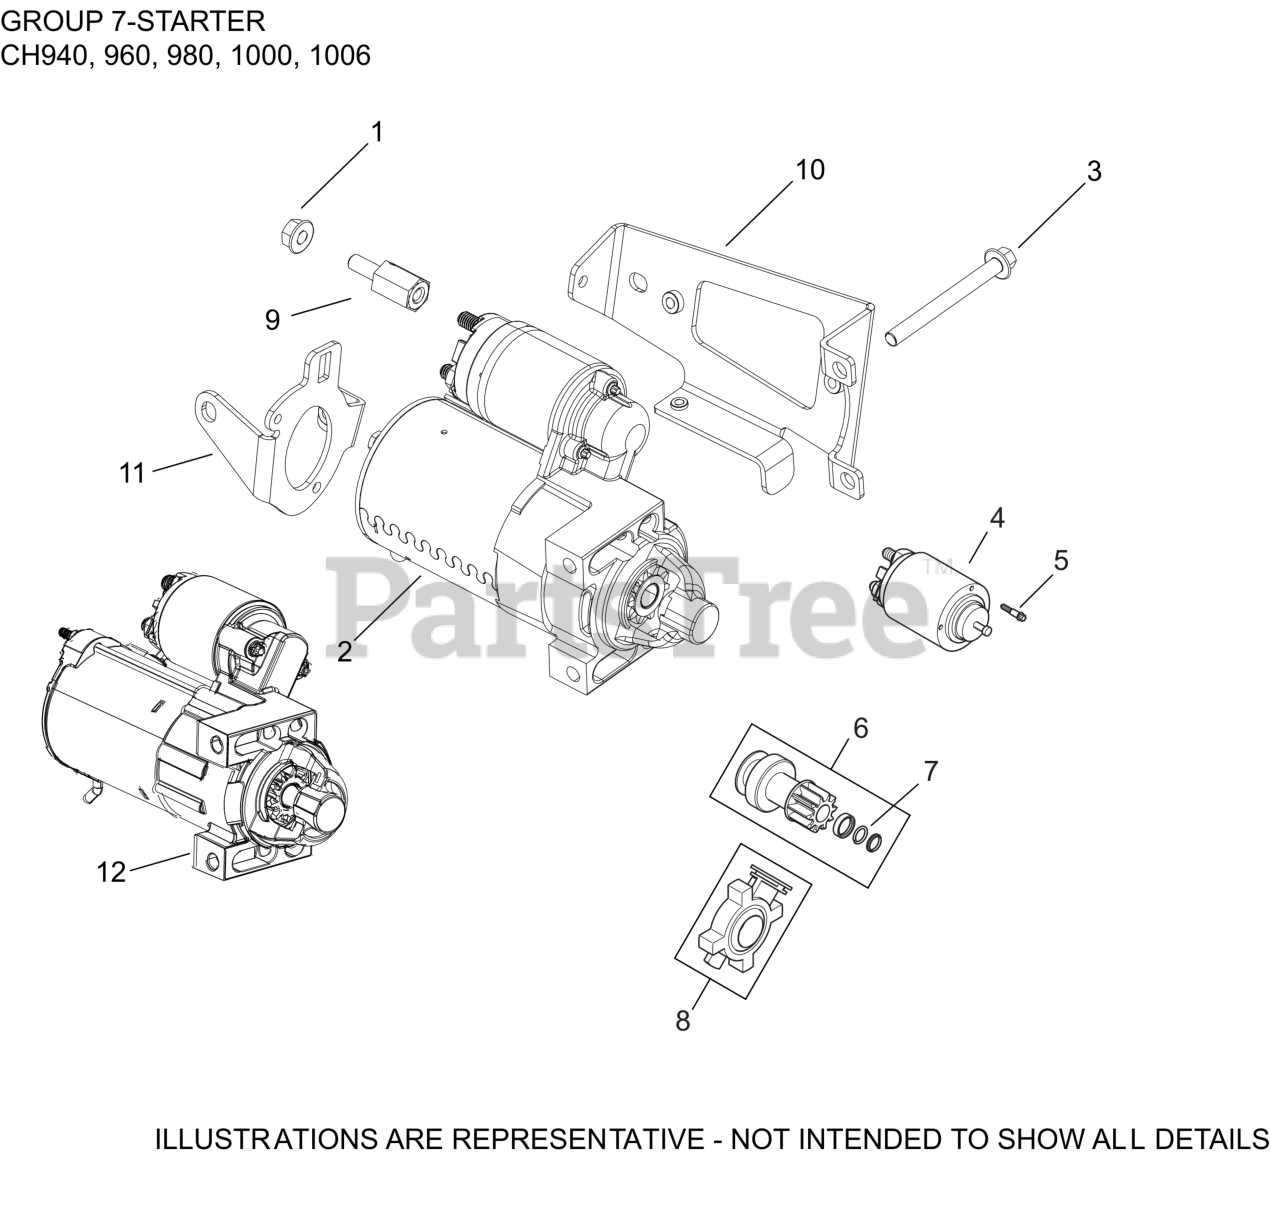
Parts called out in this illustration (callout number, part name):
1	NUT, FLG M8X1.25
2	STARTER, SOLENOID SHIFT (25 098 09-S)
3	SCREW, FLG M8X1.25X80
